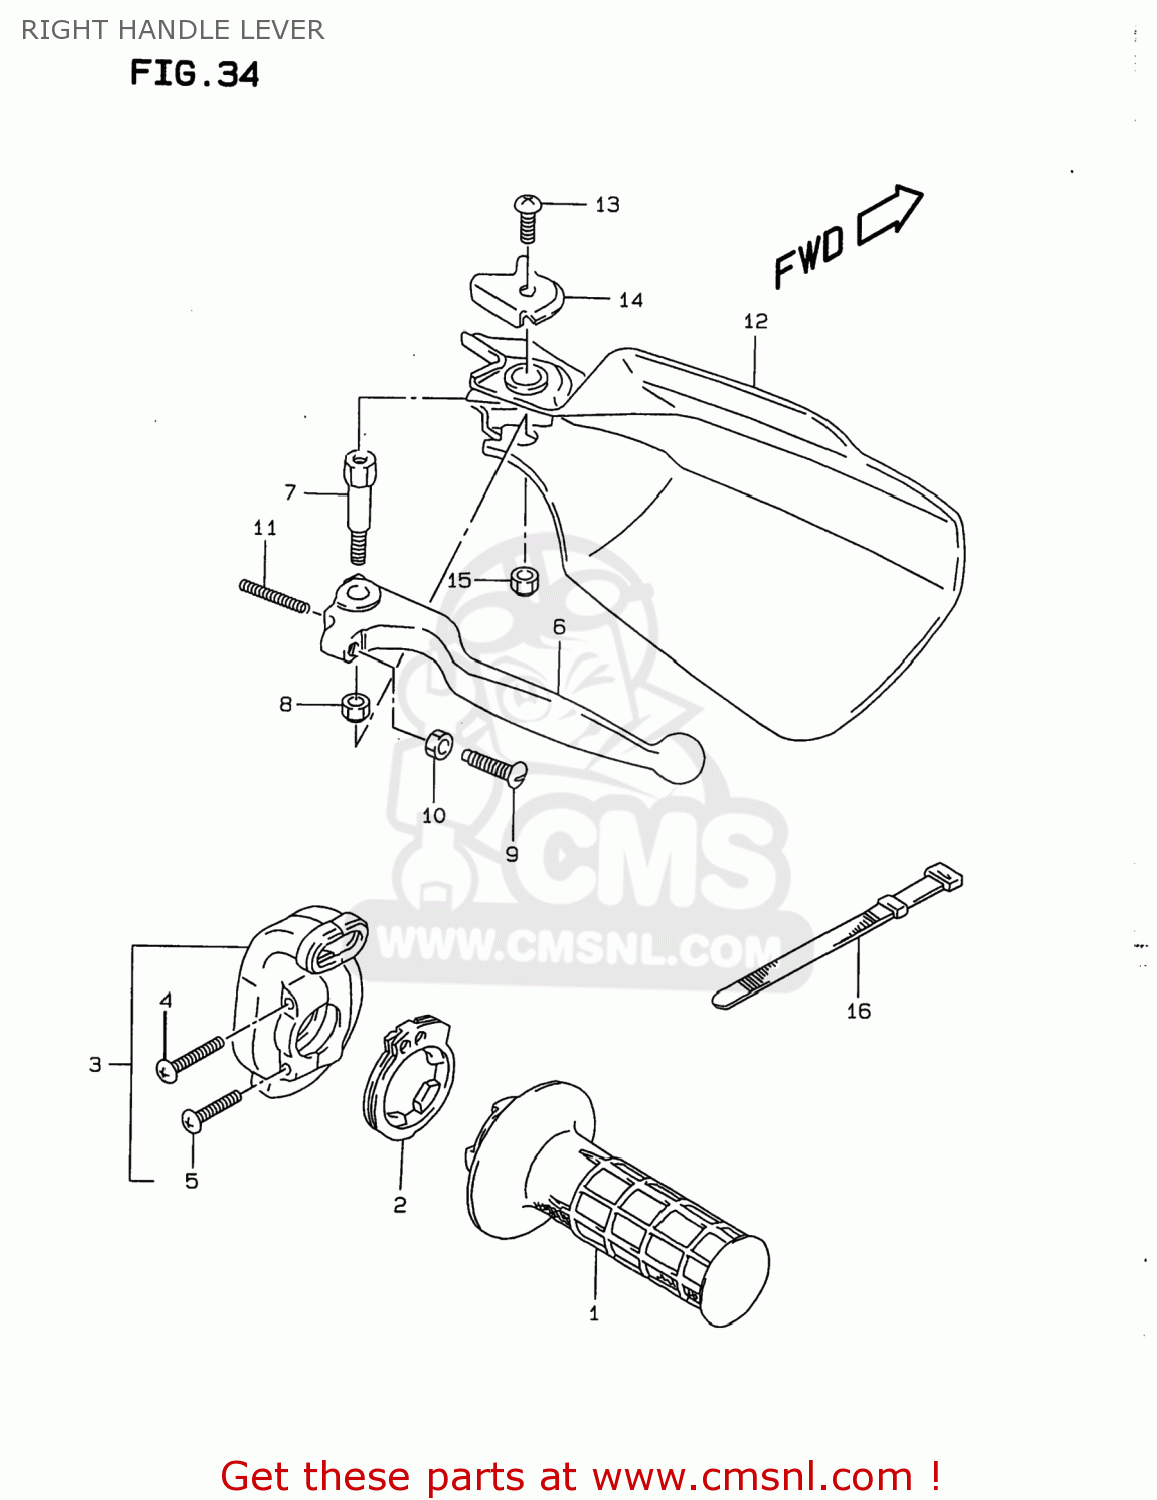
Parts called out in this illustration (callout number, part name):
1	GRIP,THROTTLE
2	ROTOR,THROTTLE GRIP
3	CASE ASSY,THROTTLE
4	SCREW(5X25)
5	SCREW
6	LEVER,BRAKE
7	BOLT,BRAKE LEVER PIVOT
8	NUT 6MM
9	BOLT,ADJUST
10	NUT
11	SPRING,RETURN
12	COVER,KNUCKLE,R
13	SCREW
14	PLATE,KNUCKLE COVER,R UPR
15	NUT 6MM
16	CLAMP(L:120)
